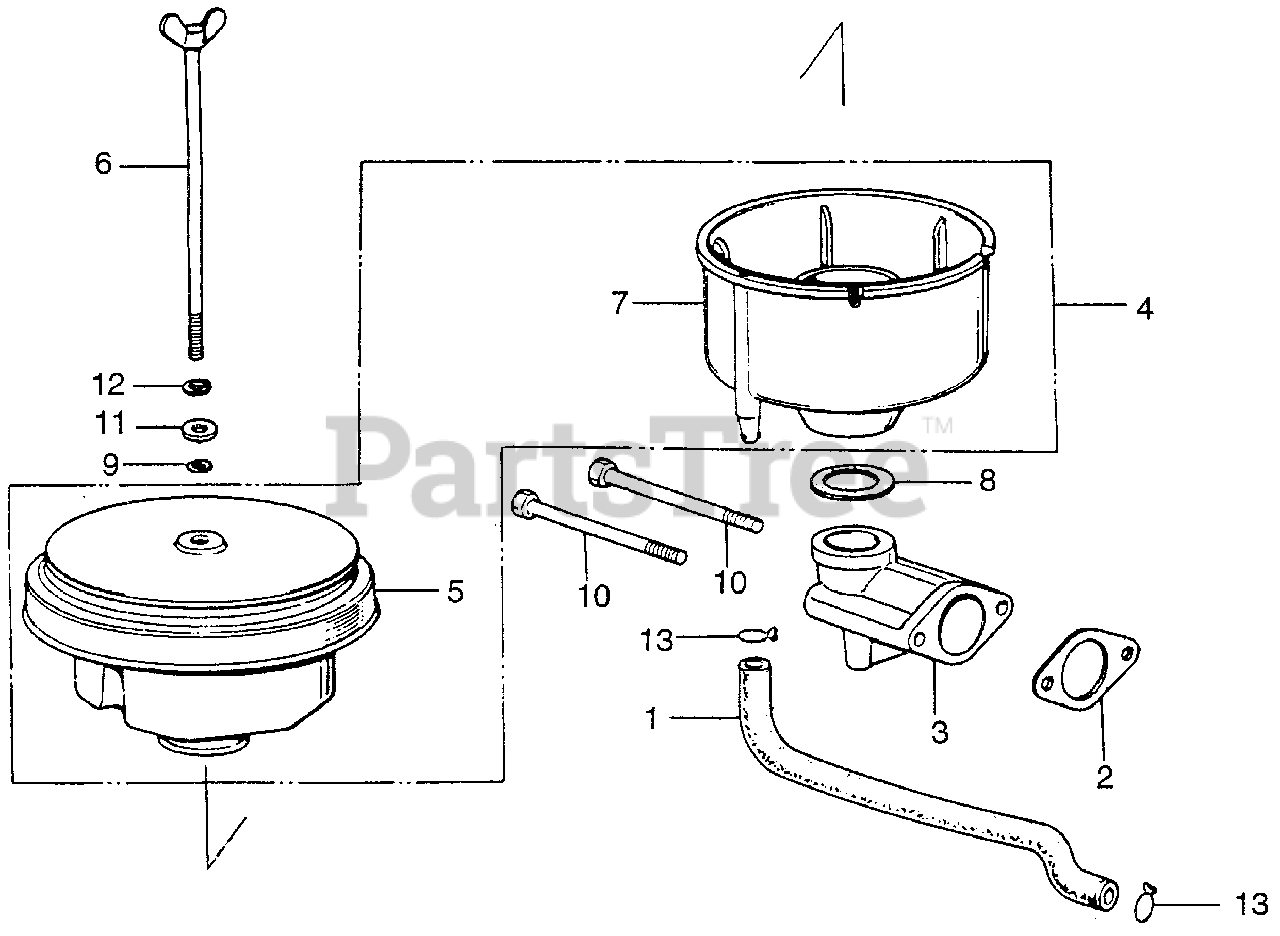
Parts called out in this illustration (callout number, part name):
1	TUBE, BREATHER
2	GASKET, AIR CLEANER (NOT AVAILABLE)
3	ELBOW, AIR CLEANER
4	AIR CLEANER ASSY., OIL BATH
5	BODY KIT, AIR CLEANER (NOT AVAILABLE)
6	BOLT, AIR CLEANER
7	PAN, CLEANER OIL
8	GASKET, AIR CLEANER (NOT AVAILABLE)
9	O-RING (5X2.4)
9	O-RING (4.9X2.5)
10	BOLT, HEX. (6X70)
11	WASHER, PLAIN (6MM)
12	WASHER, SPRING (6MM)
13	CLIP, TUBE (B12.5)
